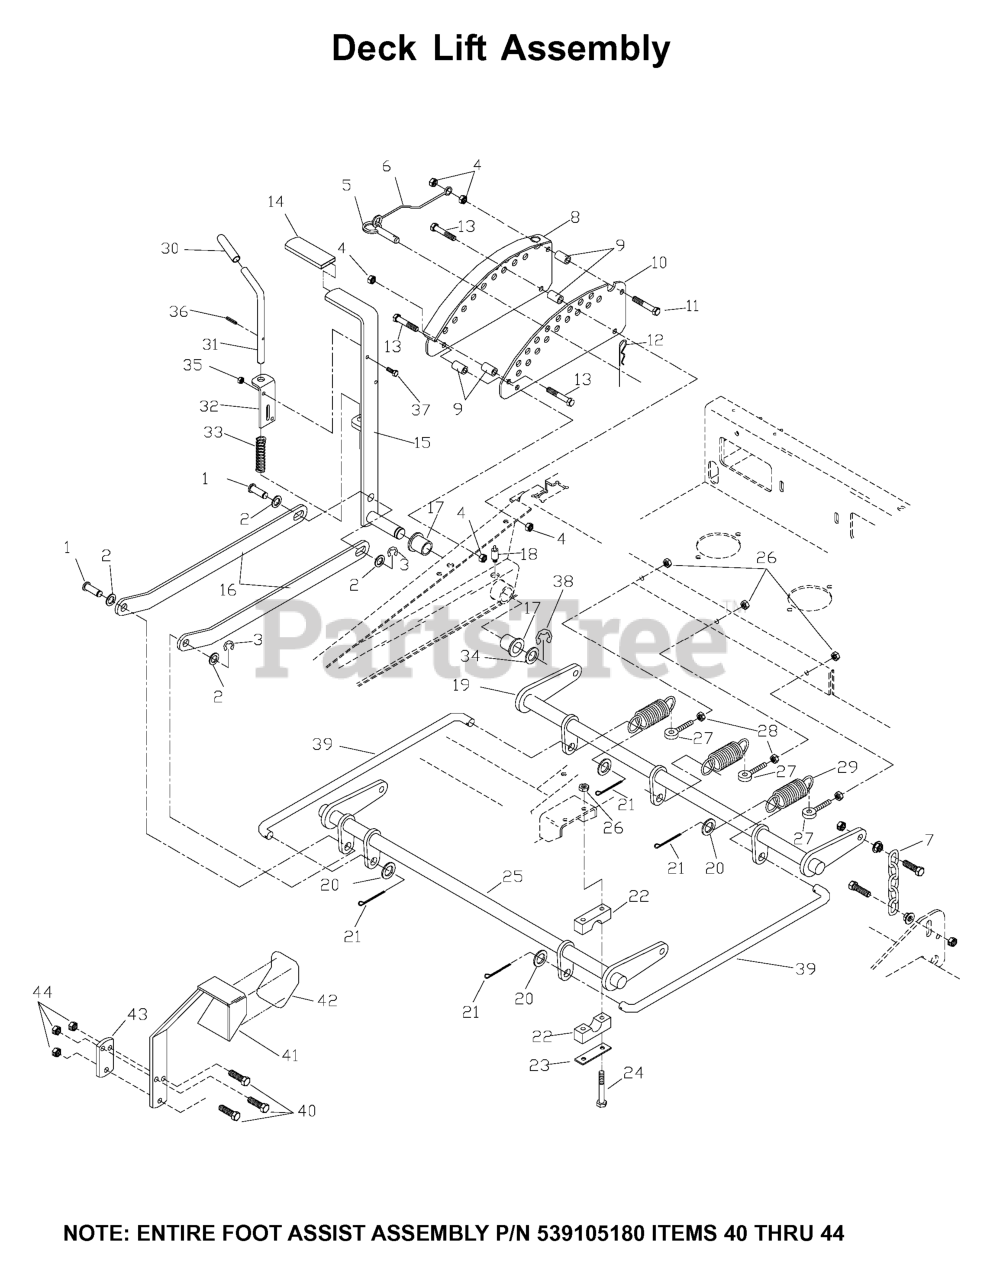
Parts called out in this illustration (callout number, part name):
1	CLEVIS PIN
3	E-RING 5/8
4	NUT 3/8C CENTERBLOCK
7	LIFT CHAIN
8	ADJ. PLATE WLDMNT
9	DECK LIFT SPACER
10	ADJ. PLATE PAINTED
11	HCS 3/8C X 2 1/2
12	HAIRPIN #4
13	HCS 3/8C X 2 1/4
15	LIFT LEVER WLDMT
16	LIFT LINKAGE,PAINTED
17	BUSHING, FLANGED
18	GREASE ZERK LONG
19	LIFT SHAFT
20	WASHER 5/8 FLAT
21	COTTER PIN
22	PILLOW BLOCK
23	REINFORCEMENT BAR
24	BOLT 5/16C X 2 1/2
25	FT. LIFT SHAFT
26	NUT 5/16C CENTERLOCK
27	EYEBOLT, RH
28	NUT 5/16C WHIZ
29	DECK LIFT SPRING
32	PIN MT, UPPER
34	BSHG .875 X 1.375 X .074 ZD
35	NUT 1/4C CENTER LOCK
36	ROLL PIN 3/16 X 1-1/4 ZD
37	HCS 1/4C X 3/4 HCS
38	E-RING 7/8
39	CONNECTING LINK
40	HCS 3/8C X 1 1/2
41	LIFT PEDAL BLK
42	ANTI-SKID PAD
43	TIGHTENING PLATE BLK
44	NUT 3/8-16 NYLOC
